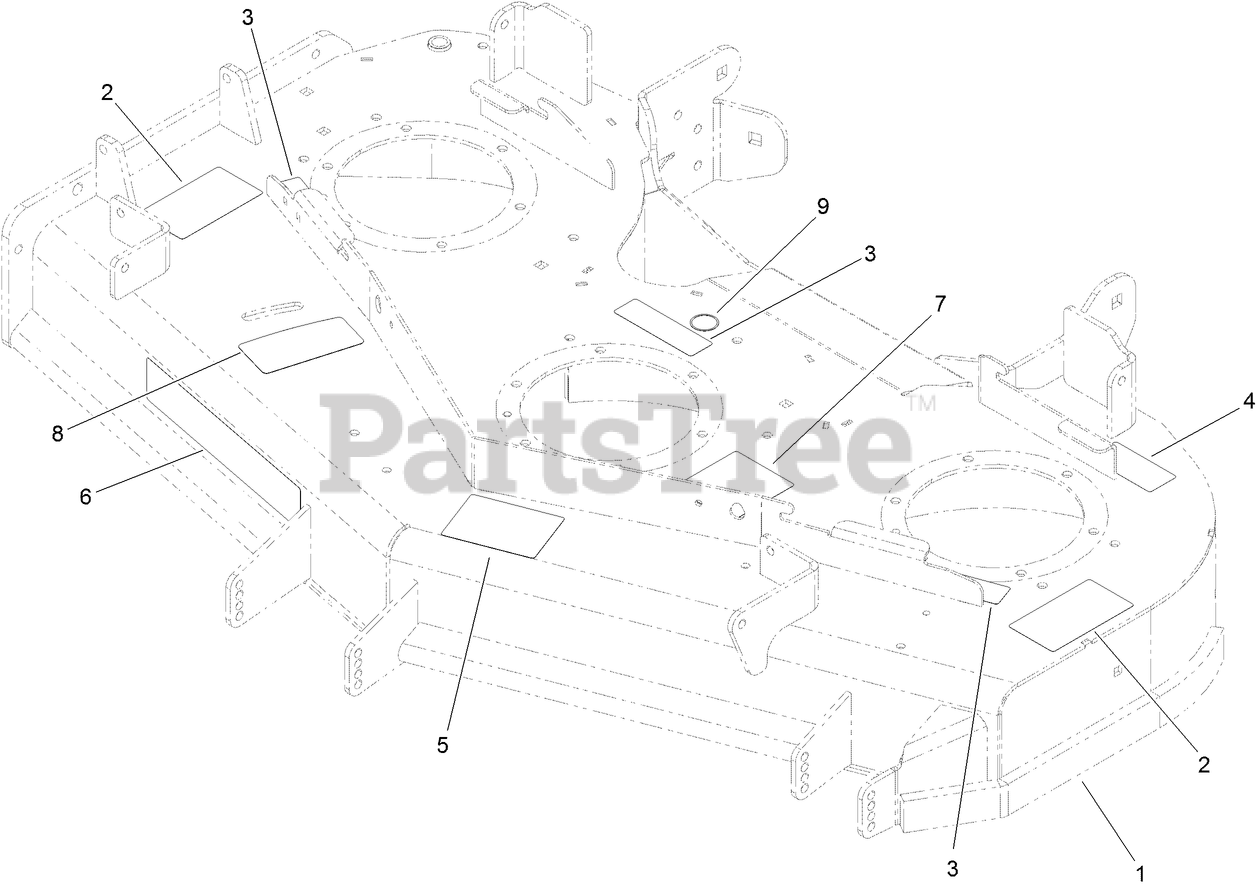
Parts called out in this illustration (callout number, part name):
1	DECK ASM
2	DECAL-DANGER
3	DECAL-COVER, MISSING
4	DECAL-BOLT TORQUE
5	DECAL-SCALP, ANTI
7	DECAL-ROUTING, DECK BELT
8	DECAL-ADJUSTMENT, BAFFLE
9	DECAL-GREASE
